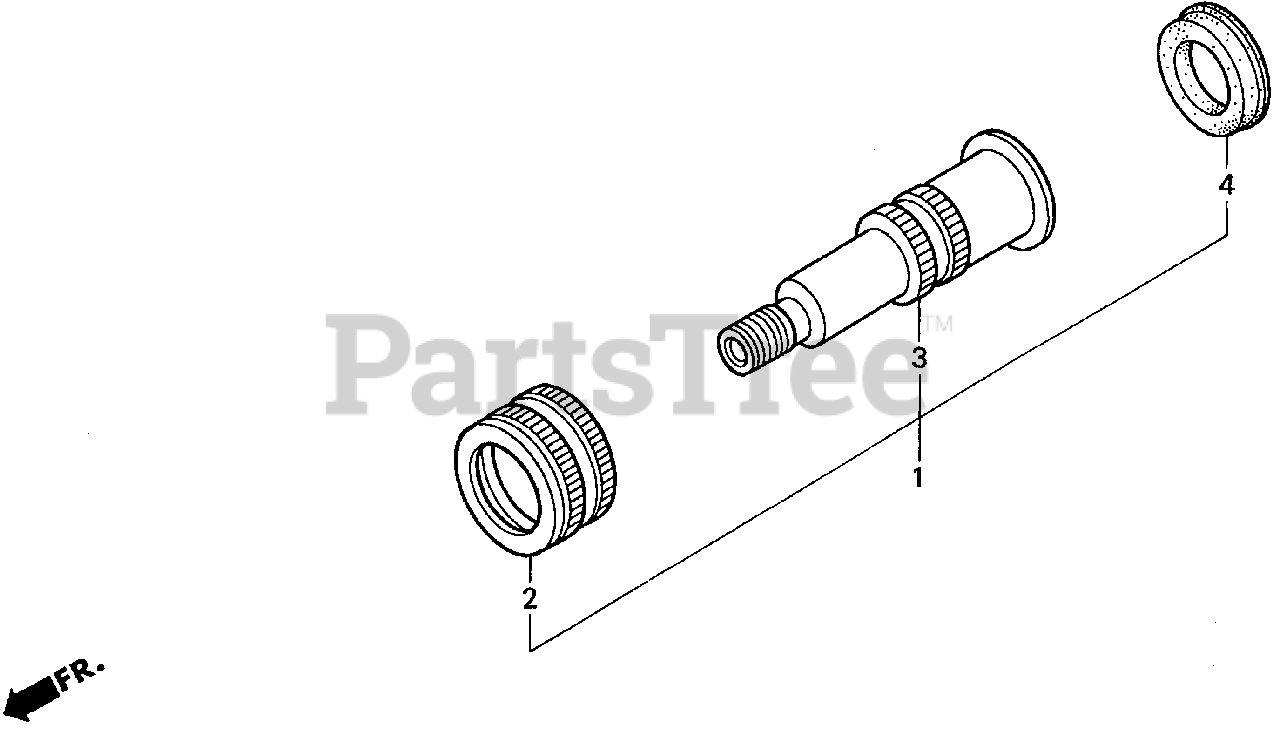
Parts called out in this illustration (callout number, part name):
1	JOINT KIT, WATER HOSE
2	NUT, WATER MOUTH
3	JOINT, WATER HOSE
4	SEAT, WATER MOUTH
